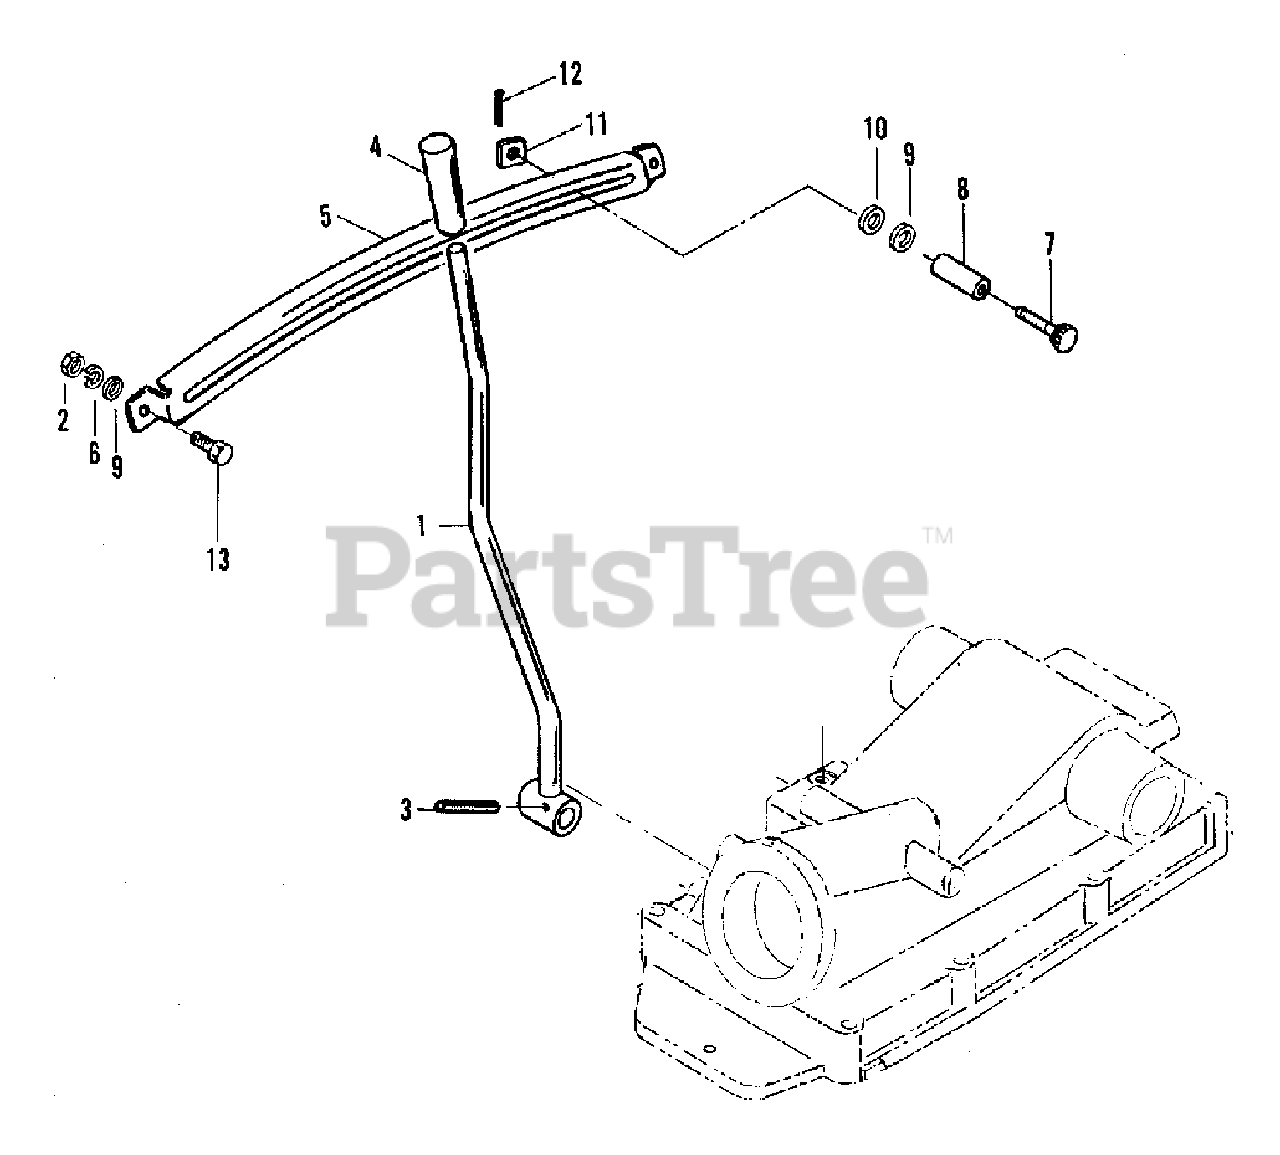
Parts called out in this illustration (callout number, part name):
3	PIN, M6 x 24, roll
4	KNOB, control
5	GUIDE, lever
6	LOCKWASHER, M8
7	KNOB, stopper
10	GASKET, stopper knob
11	NUT, stopper
12	PIN, cotter
13	CAPSCREW, M8 x 16
